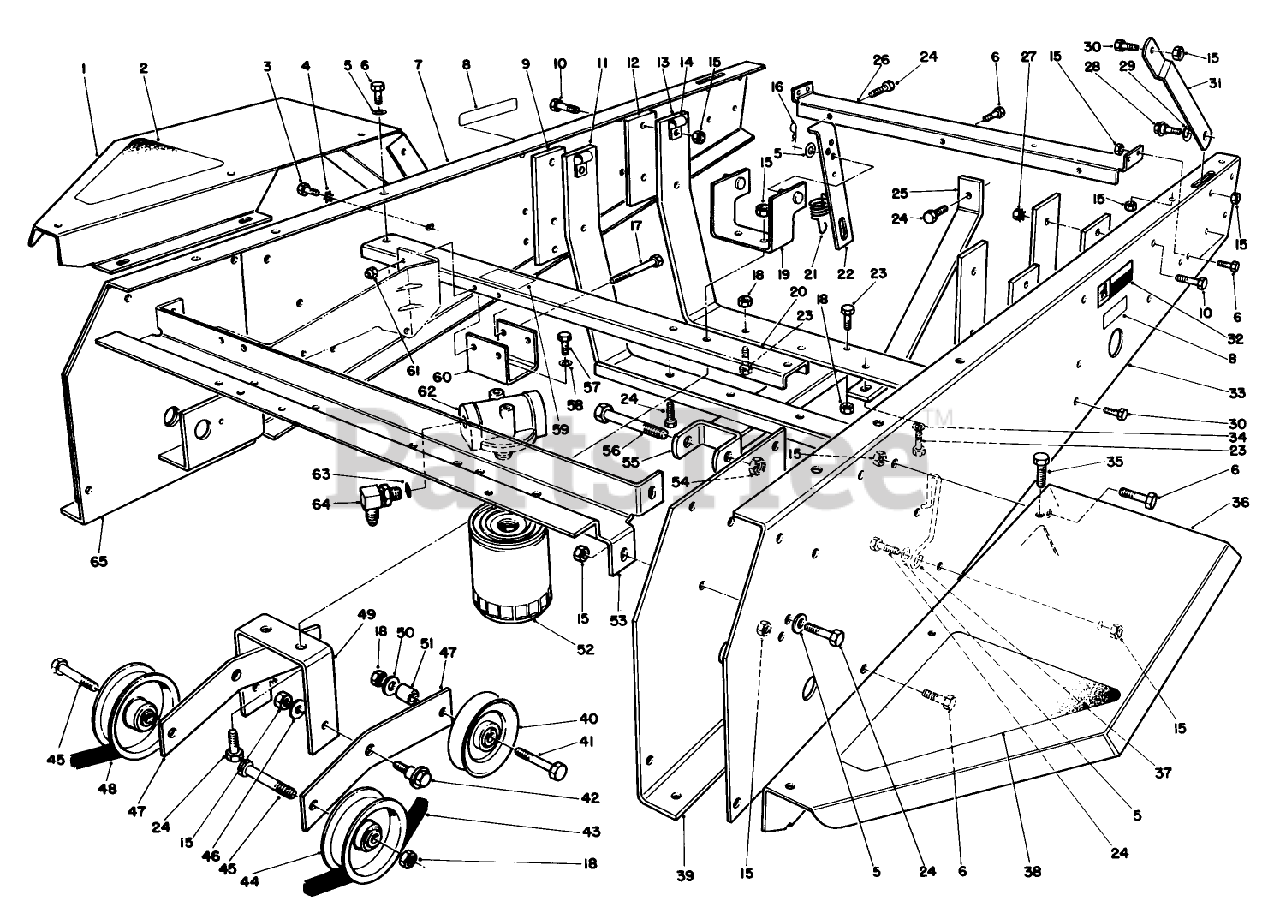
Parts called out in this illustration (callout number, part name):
3	SCREW-HH
4	WASHER-LOCK
5	WASHER-PLAIN
6	SCREW-HH
8	DECAL-ROTATING
9	FRONT ENG PLATE
10	SCREW-HH
11	ENGINE MT WA *B
12	REAR ENG PLATE
14	CLAMP-R
15	NUT-LOCK, NI
16	PIN-COTTER
17	SCREW-HH
18	NUT-LOCK, NI
20	MIDDLE CHANNEL WA *B
21	IDLER SPRING
23	SCREW-HH
24	SCREW-HH
27	NUT-KEPS
28	SCREW-SHOULDER
29	WASHER-SPRING
30	SCREW-HH
32	DECAL-HOT
34	WASHER-LOCK
35	SCREW-HHFTF
37	BELT GUIDE
41	SCREW-HH
42	SCREW-SHOULDER
43	V-BELT, JACKSHAFT
45	SCREW-HH
46	WASHER
48	V-BELT, TRACTION
50	WASHER-FLAT
51	SPACER-WEIGHT
52	FILTER-OIL, TRANSMISSION
54	NUT-LOCK
56	SCREW-HH
57	SCREW-HH
58	WASHER-LOCK
59	DECAL-OIL
60	BRACKET - FILTER HEAD
61	NUT-LOCK, NI
62	FILTER HD ASM
63	O-RING
